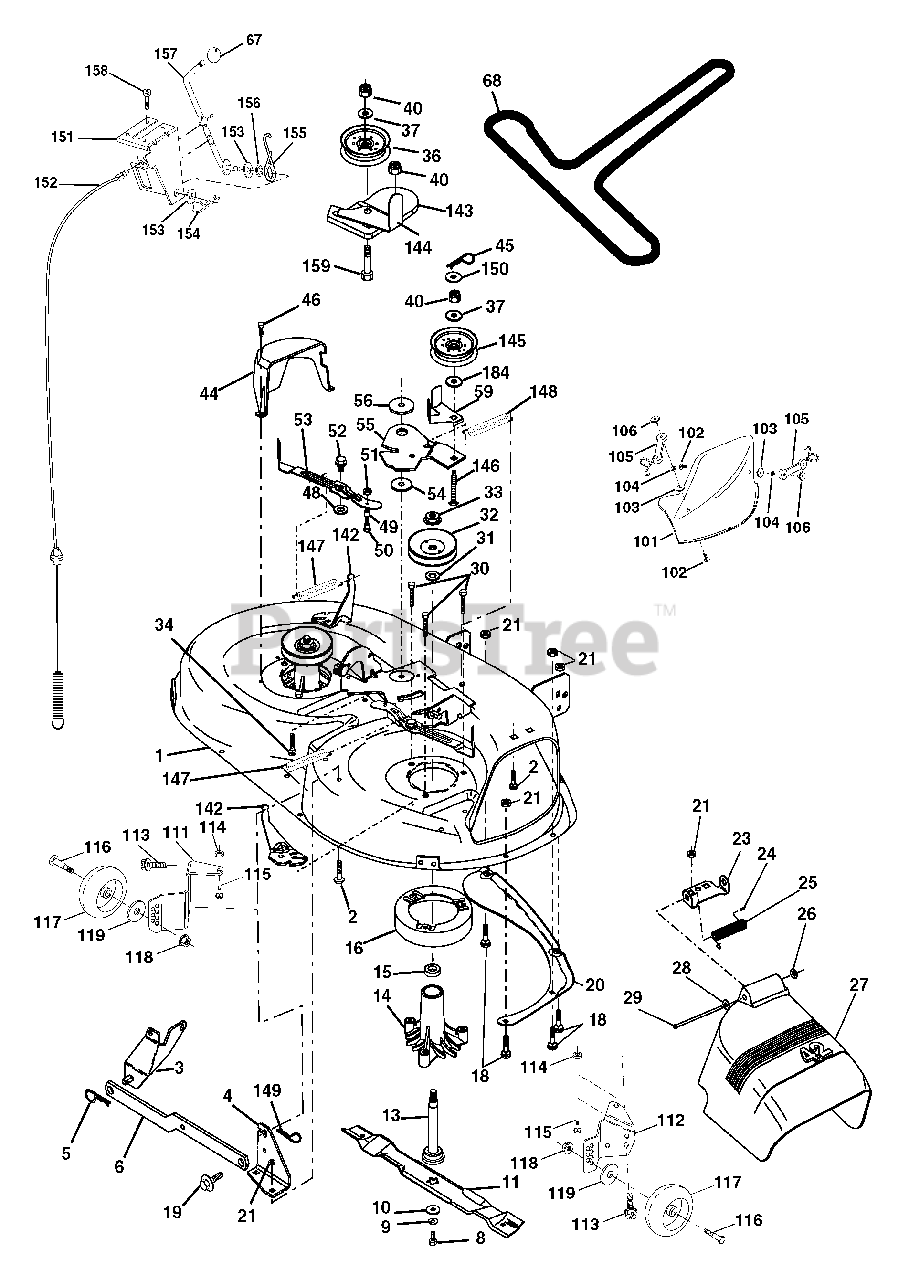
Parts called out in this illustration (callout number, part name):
1	Mower Deck Assembly, 42"
2	Bolt
3	Bracket Asm Fr. Sway Bar 3/42
4	Bracket Asm Deck 42" Sway Bar
5	Retainer Spring
6	Bar Sway Deck
8	Bolt 3/8-24 x 25 Grade 8 patched
9	Washer, Lock
10	Washer, Hardened
11	Blade
13	Shaft Assembly, Mandrel, Vented
14	Housing, Mandrel, Vented
15	Bearing, Ball, Mandrel
16	Stripper, Mower Deck
18	Bolt, Carriage 5/16-18 x 5/8
19	Bolt, Shoulder
20	Baffle, Vortex
21	Nut
23	Bracket, Deflector Mower 42"
24	Cap, Sleeve 80 x 112 Blk Mower
25	Spring, Torsion, Deflector 2 52
26	Nut, Push Phos & Oil
27	Shield, Deflector 42" Blk
28	Washer 11/32 x 5/8 x 16 Gauge
29	Rod, Hinge 42" 6 75 W/G
30	Screw Thdrol Hex
31	Washer, Spacer Mower Vented
32	Pulley, Mandrel
33	Nut, Toplock
34	Bolt
36	Pulley, Idler, Flat
37	Washer 13/32 x 13/16 x 16 Ga.
40	Nut
44	Guard, Mandrel, LH
45	Retainer
46	Screw, Thdrol 1/4-20 x 5/8 T
48	Washer, Hardened
49	Roller Assembly, Cam Follower
50	Bolt, Shoulder #10-24 Grade 5
51	Locknut
52	Bolt, Shoulder 5/16-18 UNC
53	Arm Assembly, Pad, Brake
54	Washer, Hardened
55	Arm, Idler
56	Spacer, Retainer
59	Guard TUV Idler
67	Knob
68	V-Belt, 42" Mower
101	Mulcher Cover
102	Screw Pan Hd Phillips 10-24 x 5/8
103	Washer Flat
104	Washer, Lock
105	Latch Assembly
106	Nut, Weld
111	Bracket, Gauge, Wheel LH
112	Bracket, Gauge, Wheel RH
113	Screw Tapping 3/8-16 x .625
114	Nut, Keps 5/16 - 18 UNC
115	Bolt, Carriage 5/16-18 x 5/8
116	Bolt, Shoulder
117	Wheel, Gauge
118	Nut Centerlock 3/8-16
119	Washer 3/8 x 7/8 x 14 Ga.
142	Arm Spring Brake Mower
143	Bracket Arm Idler 42"
144	Keeper Belt 42" Clutch Cable
145	Pulley Idler Flat
146	Bolt Carriage Idler
147	Spring Extension
148	Spring Return Idler
149	Retainer Spring Yellow
150	Washer 9/32 x 3/4 x 16 Ga.
151	Bracket Clutch Cable
152	Clutch Cable 42"
153	Washer Flat 3/8" Type B
154	Spring Retainer
155	Spring Retention LVR CLTCH CAB
156	Spacer Clutch Cable
157	Rod Clutch Cable 3/8"
158	Screw Hex Thd Cut 1/4-20 x 1/2
159	Bolt Rdhd Sqn 3/8-16 UNC x 1-3/4
184	Washer 13/32 x 7/8 x 10 Ga.
